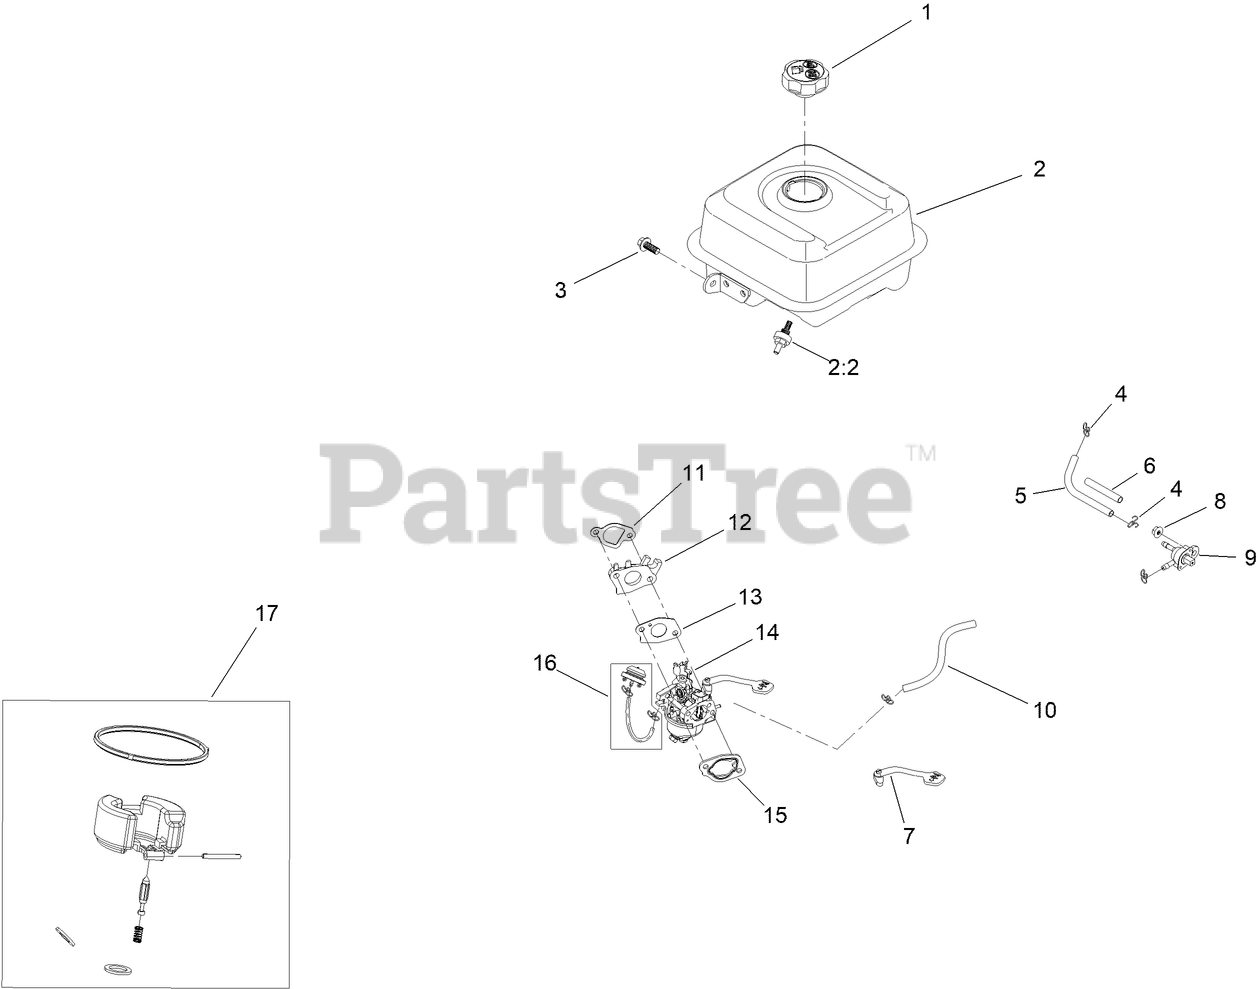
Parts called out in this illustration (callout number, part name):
1	CAP-FUEL
2	FUEL TANK AND FILTER ASM
2:2	FILTER-FUEL
3	SCREW-HHF
4	CLIP-HOSE
5	HOSE-FUEL
6	SLEEVE-ABRASION
7	LEVER-CHOKE
8	NUT-FLANGE
9	VALVE-FUEL
10	HOSE-FUEL
11	GASKET-CARBURETOR
12	INSULATOR-CARBURETOR
13	GASKET-CARBURETOR
14	CARBURETOR ASM
15	GASKET-CARBURETOR
16	PRIMER KIT
17	INTERNAL CARB SERVICE KIT
